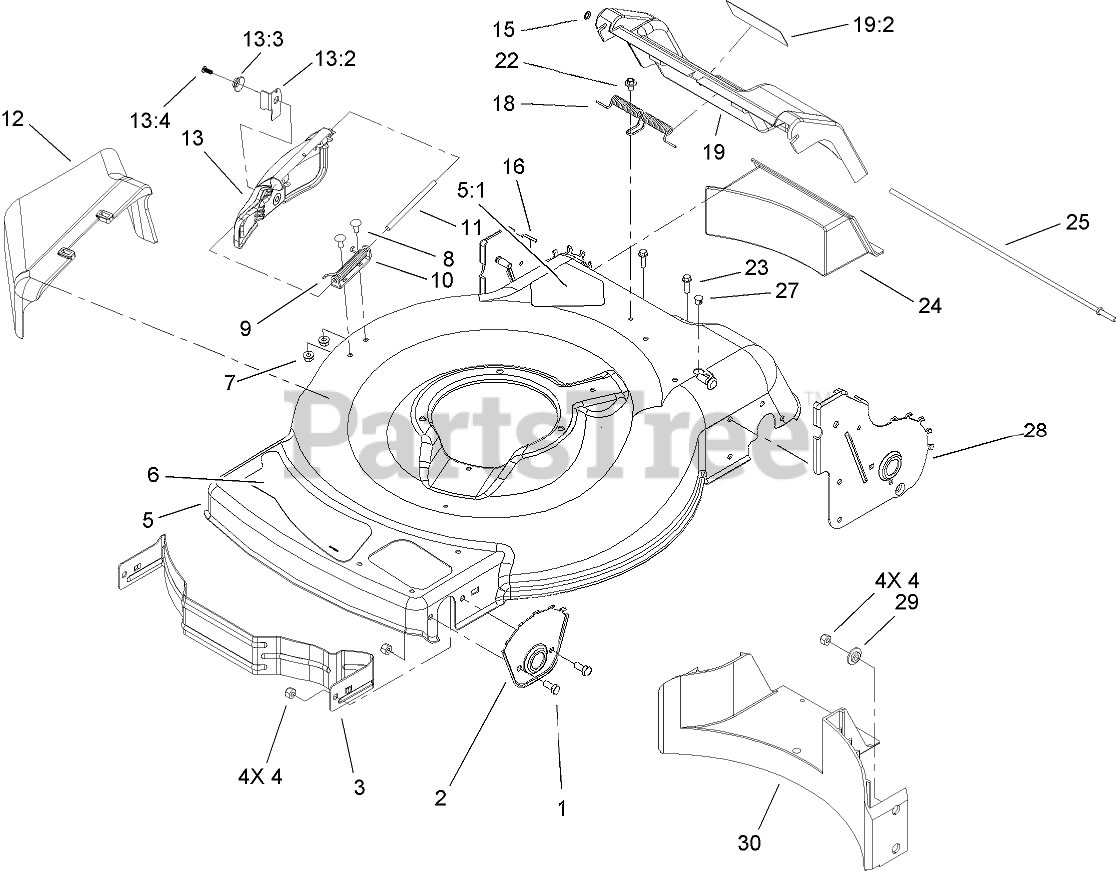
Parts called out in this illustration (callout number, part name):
1	SCREW-HH
2	Plate-HOC, Front
3	Baffle-Front
4	NUT-LOCK, NI
5	HOUSING
5:1	DECAL-DANGER
6	Decal-Deck
7	NUT-HHF
8	SCREW-CARR
9	SPRING-TORSION
10	BRACKET-COVER
11	ROD-COVER
12	CHUTE-DISCHARGE, SIDE
13	DISCHARGE DOOR ASM
13:2	LATCH-DOOR
13:3	CAP-DOOR
13:4	SCREW-PLASTITE
15	NUT-PUSH
16	11 INCH RH HOC PLATE ASM
18	Spring-Door, Rear
19	REAR DOOR ASM
19:2	DECAL-WARNING
22	SCREW AND WASHER ASM
23	SCREW-HWH
24	Plug-Discharge, Rear
25	Rod-Pivot, Rear Door
27	Plug-Dome
28	11 INCH LH HOC PLATE ASM
29	Washer-Stepped
30	Baffle-Rear
